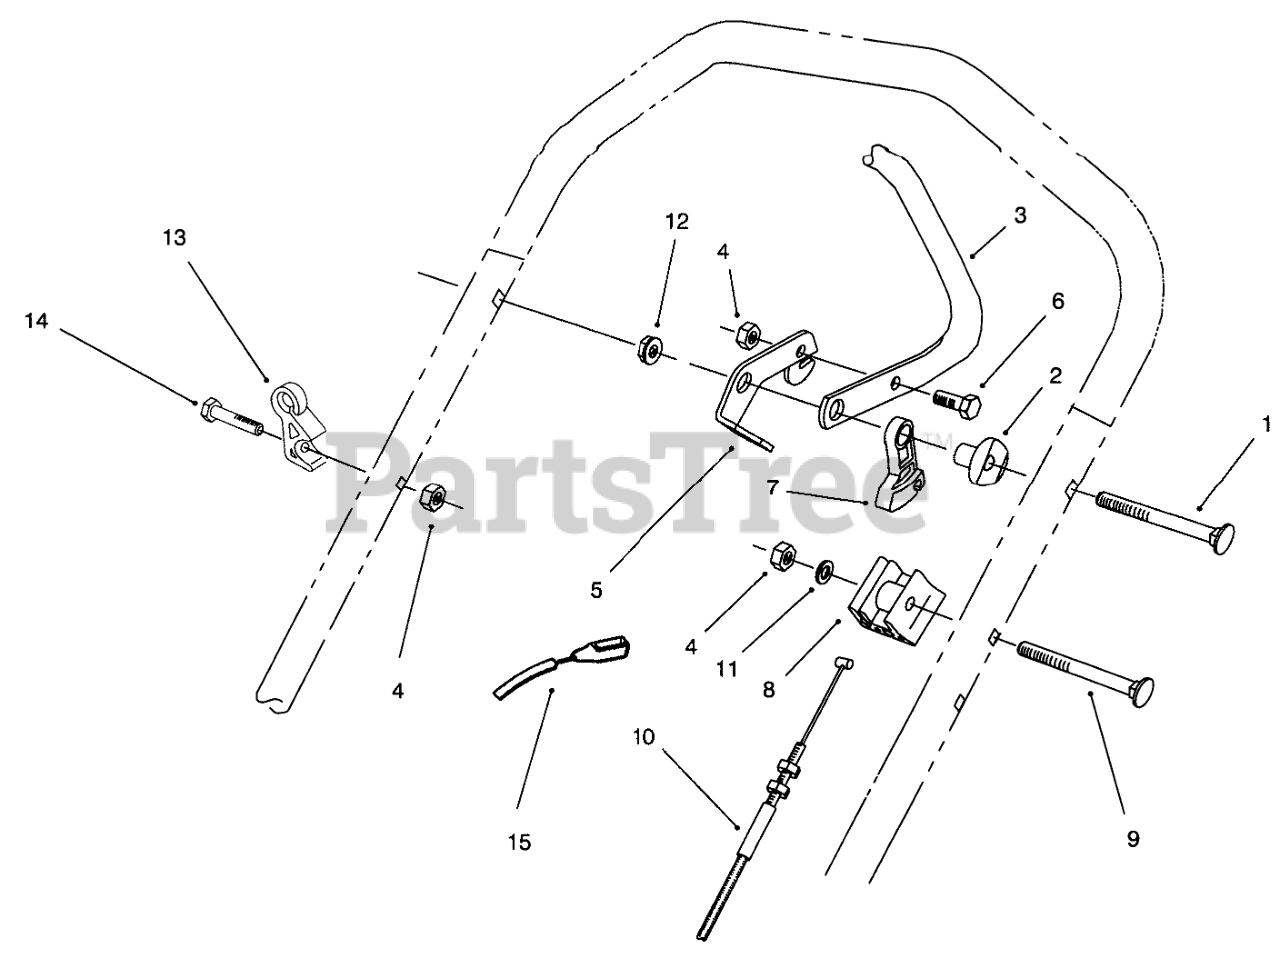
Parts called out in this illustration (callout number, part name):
1	SCREW-HANDLE
2	SPACER-SUPPORT
3	Bar-Control
4	NUT-LOCK, NI
5	LEVER-CONTROL
6	SCREW-HH
7	LEVER-TRACTION
8	SUPPORT-CABLE
9	SCREW-HANDLE
10	CABLE-TRACTION
11	WASHER-FLAT
12	NUT-LOCK, NI
13	GUIDE - ROPE
14	.250-20X1.625 HH SCREW
15	CABLE-BRAKE
